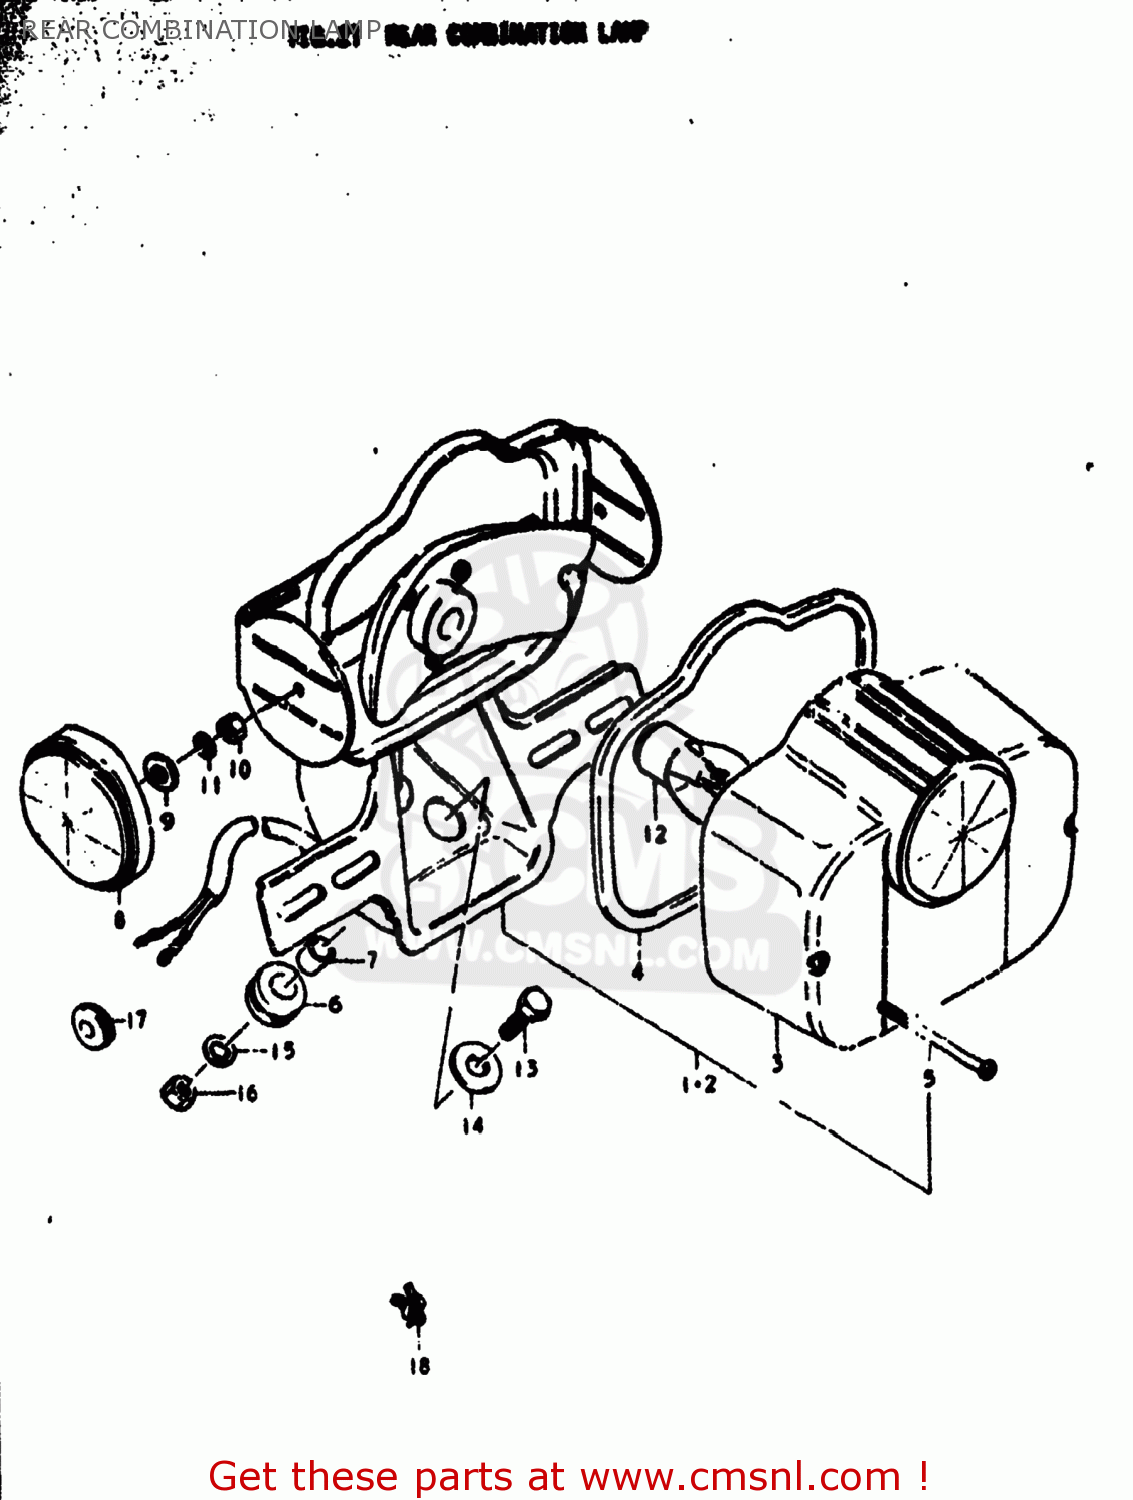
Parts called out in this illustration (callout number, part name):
1	LAMP ASSEMBLY,REAR COMBINATION
2	LAMP ASSEMBLY,REAR COMBINATION
3	LENS,REAR COMBINATION LAMP
4	GASKET (NAS)
5	SCREW
6	CUSHION
7	SPACER,REAR COMBINATION LAMP
8	REFLECTOR,REFLEX
9	WASHER,REAR COMBINATION LAMP
10	NUT
11	LOCK WASHER
12	BULB(6V32/3CP,STANLEY)
13	BOLT
14	WASHER
15	WASHER
16	NUT
17	GROMMET
18	GUIDE,WIRING HARNESS
